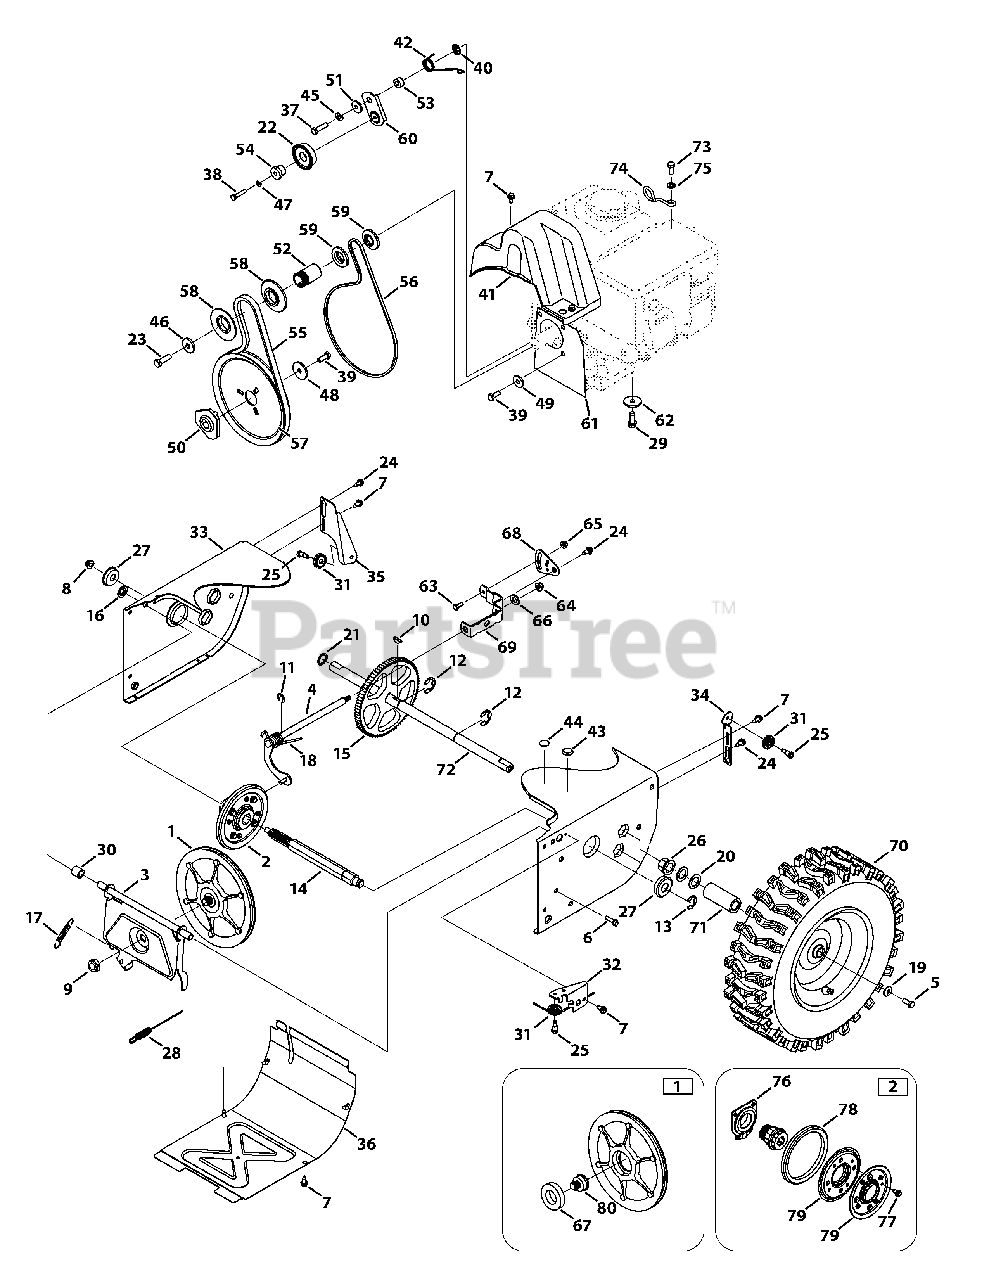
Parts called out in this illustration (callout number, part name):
1	Disc Assembly, Friction Wheel
2	Friction Wheel Assembly, 5.5 OD
3	Friction Wheel Support Bracket
4	Rod Shift Assembly
5	Hex Head Screw, 5/16-24 x .750
6	Taptite Screw, 1/4-20 x 1.000
7	Taptite Screw, 1/4-20 x .625
8	Flange Lock Nut, 3/8-16
9	Flange Nut, 5/8-18
10	Hi-pro Key, 3/16 x 3/4 Dia.
11	E-ring
12	Retaining E-ring, .875 Dia.
13	E-ring, .750 Dia.
14	Hex Shaft, 7-Tooth
15	Gear, 80-Tooth
16	Speed Nut, .500
17	Extension Spring
18	Torsion Spring, .750 x .968
19	Bell Washer, .340 x .872 x .060
20	Flat Washer, .793 x 1.24 x .060
21	Flat Washer, .75 x 1.00 x .060
22	Idler Pulley Assembly
23	Hex Screw, 3/8-24 x 1.25
24	Shoulder Screw, .368 x .113, 1/4-20
25	Shoulder Screw, 1/4-28, .340 x .355
26	Hex Flange Bearing
27	Ball Bearing, 17 x 40 x 12
28	Wheel Clutch Cable, 44.95"
29	Sems Screw, 3/8-16 x 1.00
30	Spacer, .508 ID x .75 OD x .68
31	Cable Roller
32	Auger Cable Front Guide Bracket
33	Frame
34	Auger Cable Guide Bracket
35	Drive Cable Guide Bracket
37	Hex Screw, 5/16-24 x 1.25
38	Hex Screw, 1/4-20 x 1.25
39	Hex Screw, 5/16-24 x .875
40	Push-on Nut, .25 Dia.
41	Belt Cover
42	Torsion Spring, .850 ID x .333
43	Plug, 3/8 ID
44	Plug, 1/2 ID
45	Lock Washer, 5/16
46	Flat Washer, .406 x 1.25 x .157
47	Washer, Lock, 1/4
48	Flat Washer, .34 x 1.50 x .150
49	Shoulder Space
50	Adapter Pulley, .75 Dia.
51	Shoulder Spacer, .3175 x .50 x .0975
52	Spacer, .875 ID x 1.185 OD
53	Spacer, .340 x .750 x .330
54	Shoulder Space, .260 x .785 x .538
55	Auger Drive Belt
56	Wheel Drive Belt
57	Auger Drive Pulley, 8.1 x .5
58	Pulley Half, 2.600 OD
59	Pulley Half, 3/8 x 1.716 OD
60	Wheel Drive Idler Bracket
61	Cover Plate
62	Washer, Flat, .38 x 1.38 x .125
63	Hex Head Screw, 1/4-20 x .620
64	Flange Lock Nut, 5/16-18
65	Flange Lock Nut, 1/4-20
66	Washer, Flat, .469 x .875 x .105
67	Ball Bearing, 30 x 55 x 13
68	Speed Selector Pivot Bracket
69	Speed Selector Shift Bracket
70	X-Trac Wheel Assy., LH, 15 x 5 x 6
70	X-Trac Wheel Assy., RH, 15 x 5 x 6
71	Spacer, 1.25 x .75 x 3.0
72	Axle, .75 x 22
73	Hex Head Screw, 1.25 x 20
74	Cable Guide
75	Washer, Flat, .330 x .630 x .0635
76	Bearing Assembly
77	Screw, 1/4-14 x .625
78	Friction Wheel Rubber
79	Friction Wheel Plate
80	Disc Bearing Friction Pin
